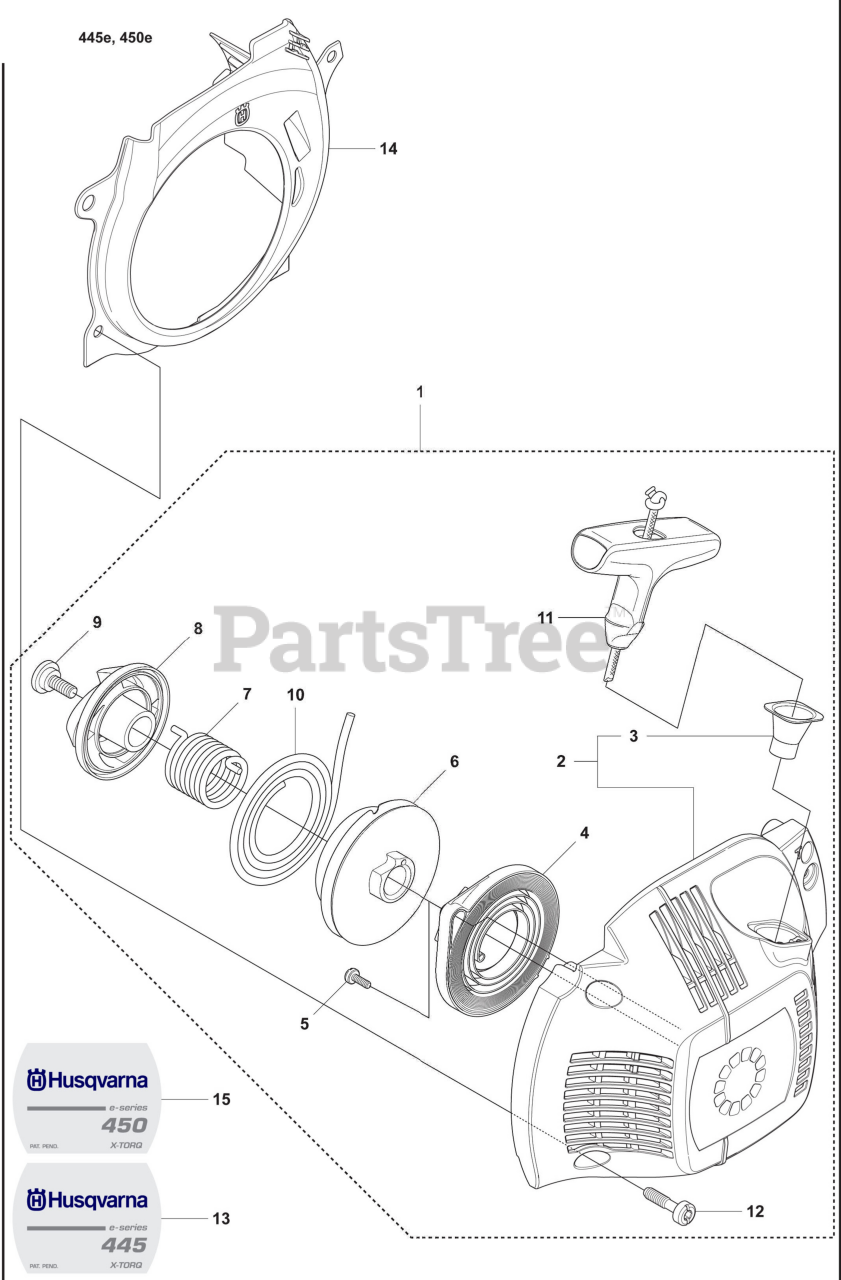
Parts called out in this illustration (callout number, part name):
1	Starter Assembly
2	Starter Housing
4	Return Spring
6	Starter Pulley
8	Starter Hub, EPS
9	Shoulder Screw
10	Starter Rope
12	Recoil Starter Screw
14	Air Cooling Conductor
